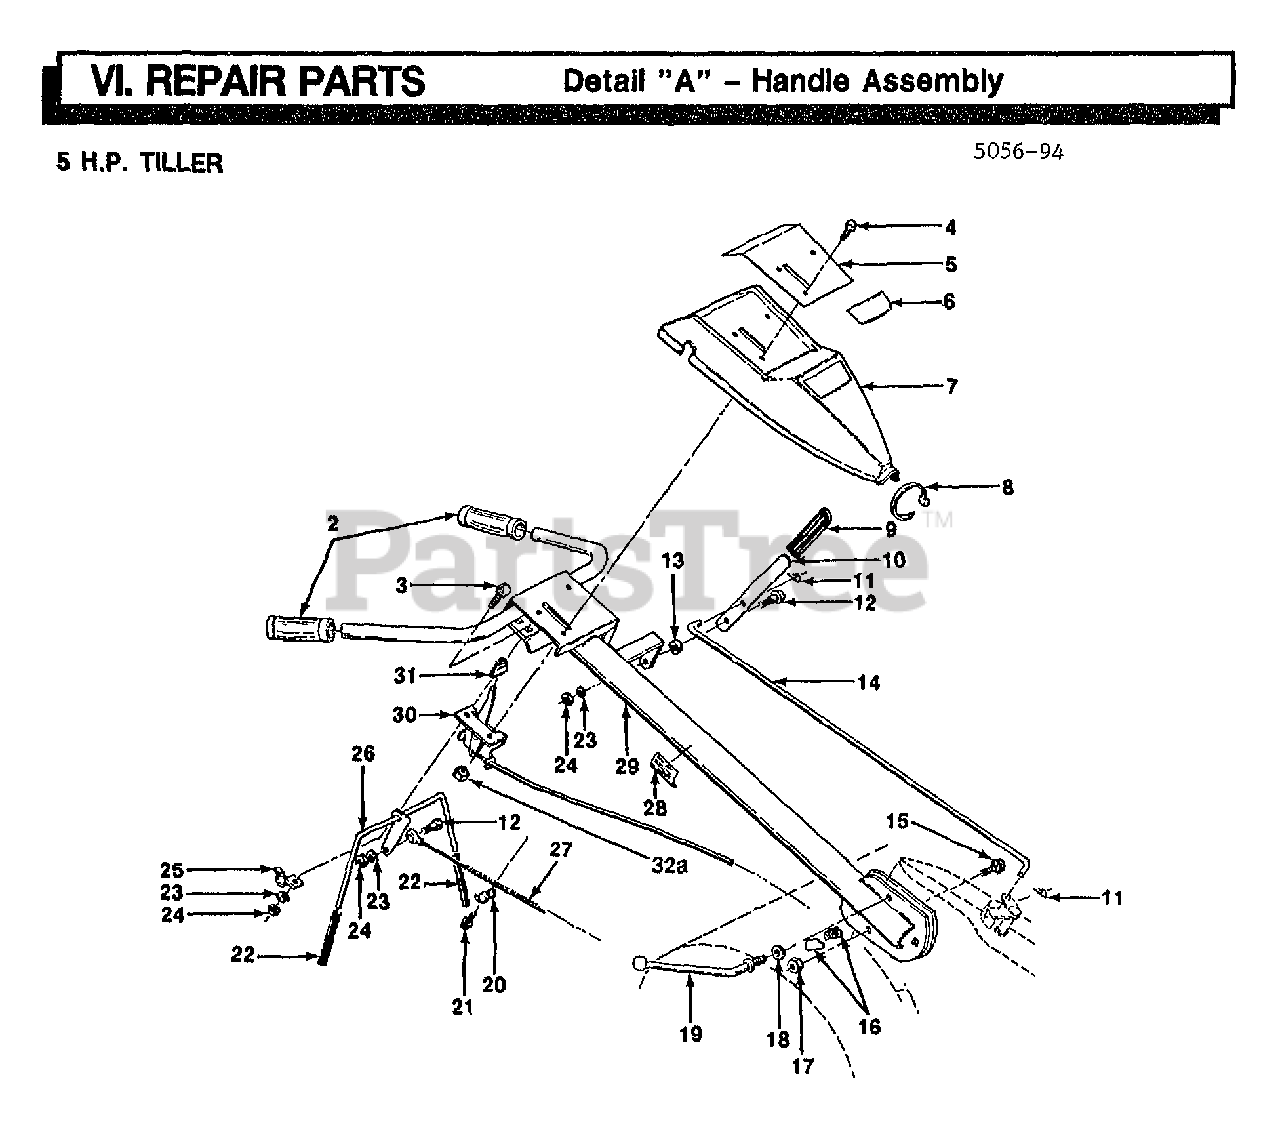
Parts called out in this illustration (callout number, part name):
3	BOLT
4	SCREW
6	DECAL, CONTROL PANEL
7	PANEL CONTROL
8	TIE CABLE CRT
9	GRIP T
10	SHIFT HANDLE CRT
11	RETAINER M
12	SHOULDER BOLT ST
13	GROMMET CRT
14	SHIFT ROD CRT
15	BOLT D
16	LOCK CRT
18	WASHER CRT
19	LEVER LOCK CRT
20	CONDIUT CLIP T
22	GRIP BAR CRT
23	LOCKWASHER
26	"ASSY CONTROL, BAR"
27	CABLE.CLUTCH.CRT
28	DECAL TI
30	THROTTLE CRT
31	KNOB CRT
